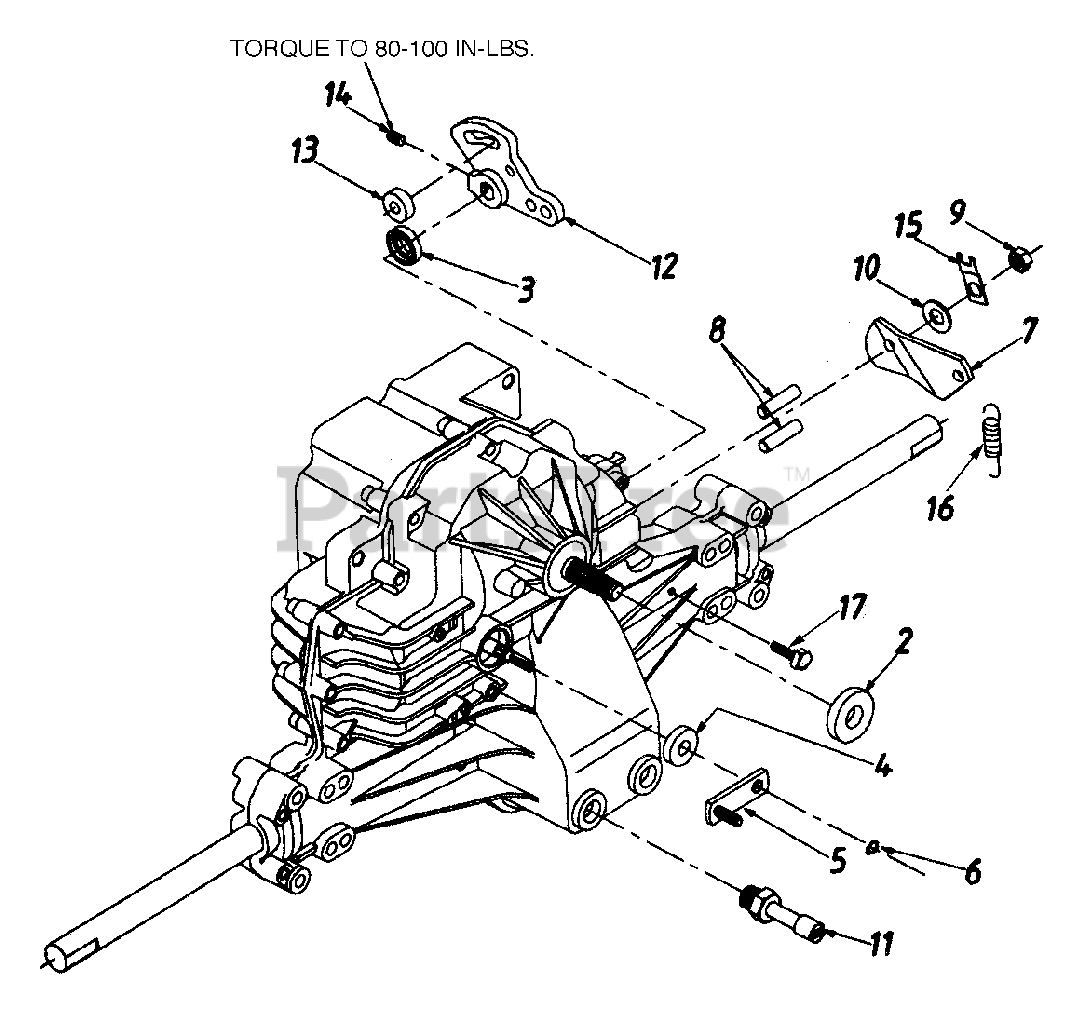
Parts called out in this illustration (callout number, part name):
4	Seal-Lip 10X25X7
6	Ring-Retaining
7	Arm-Actuating
8	Pin-Actuating
9	Nut-Hex Lock 5/16-24 UNJC
10	Washer 7/16" x 7/8" x .06"
11	Breather Ass'y.
13	Puck-Dampener
14	Set Screw
15	Strap, Locking
16	Spring, Extension
17	Self Tapp. Scr. #10-.325 x .5"
